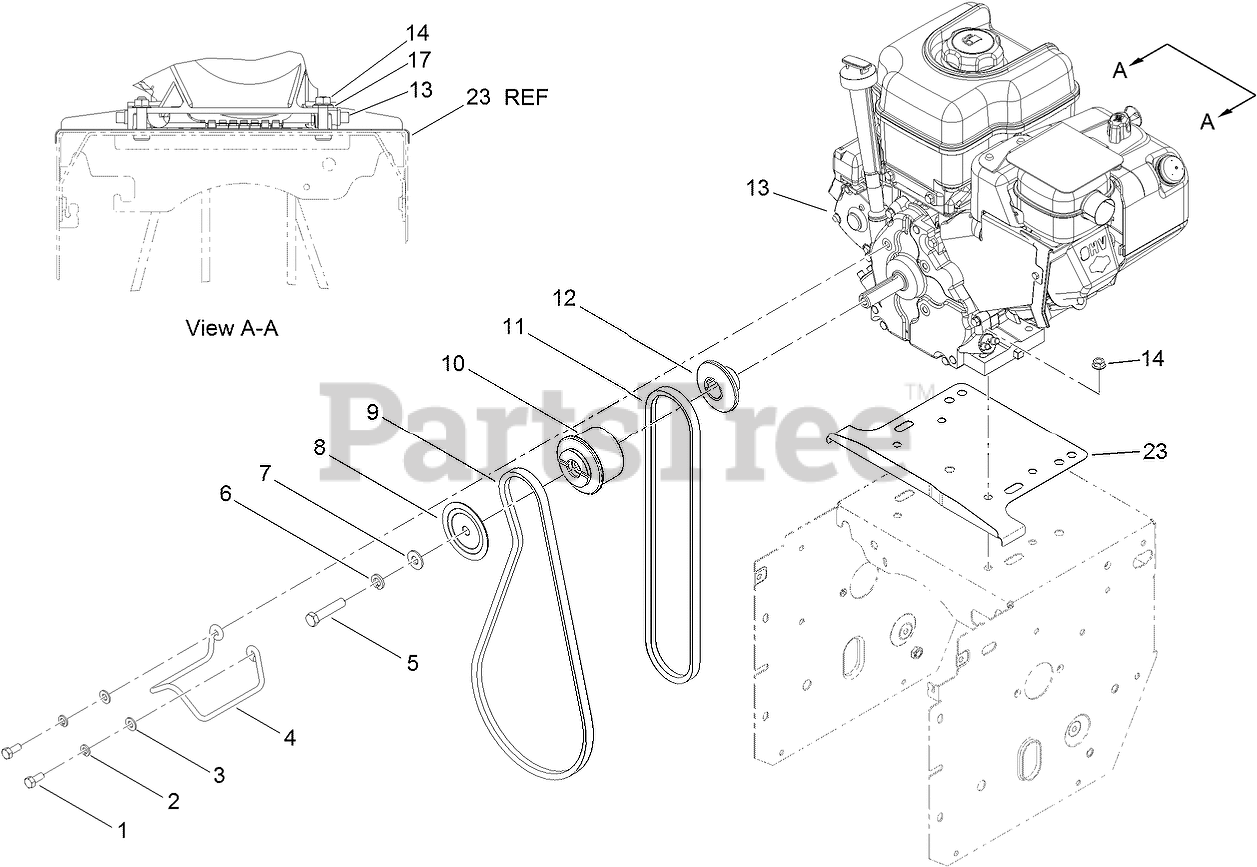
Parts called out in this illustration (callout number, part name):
1	SCREW-HH
2	WASHER-LOCK
3	WASHER-PLAIN
4	GUIDE-BELT
5	SCREW-HH
6	WASHER-LOCK
7	WASHER-FLAT
8	SHEAVE-HALF, IMPELLER
9	BELT-V
10	PULLEY-ENGINE, CENTER
11	V BELT-TRACTION
12	SHEAVE-HALF, TRACTION
14	NUT-HF
17	WASHER-FLAT
23	SHIELD-DRIVE
